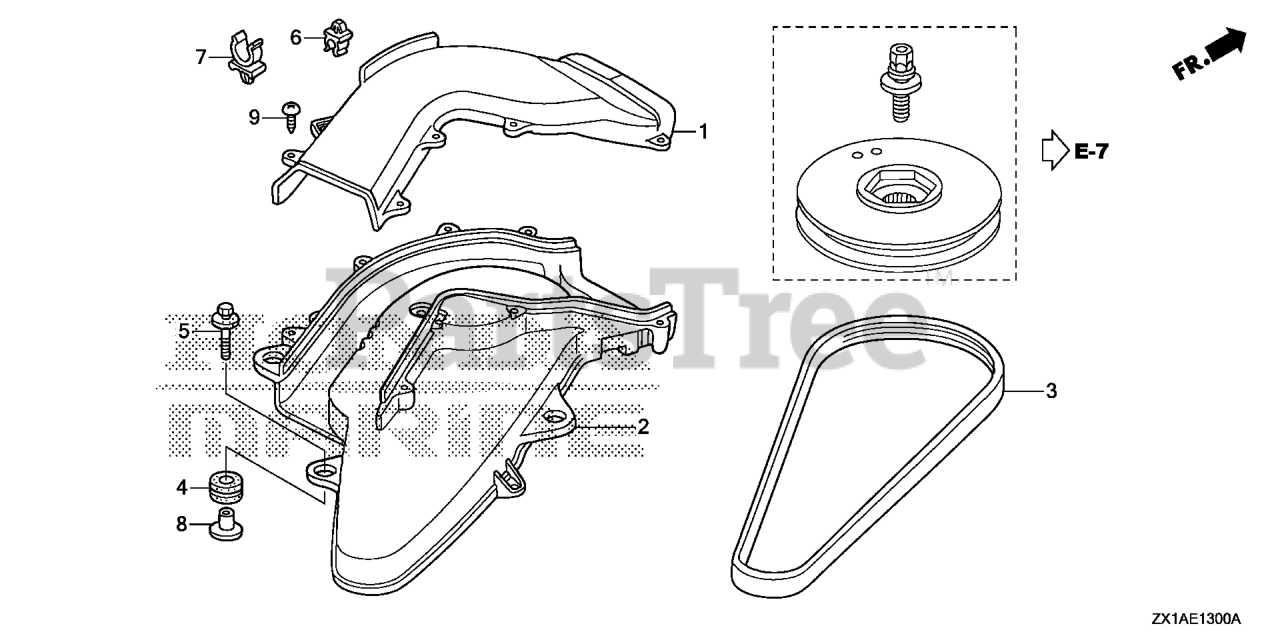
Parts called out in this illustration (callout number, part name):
1	DUCT A, MUFFLER
2	DUCT B, MUFFLER
3	BELT, ALTERNATOR (4PK810)
4	GROMMET, CASE (LOWER)
5	BOLT-WASHER (6X25)
6	CLIP, TUBE (3.5)
7	CLAMP (18.5MM)
8	COLR, CDI UNIT CASE
8	COLLAR, MODULE IGNITION CONTROL CASE (CDI)
9	SCREW, TAPPING (5X20)
